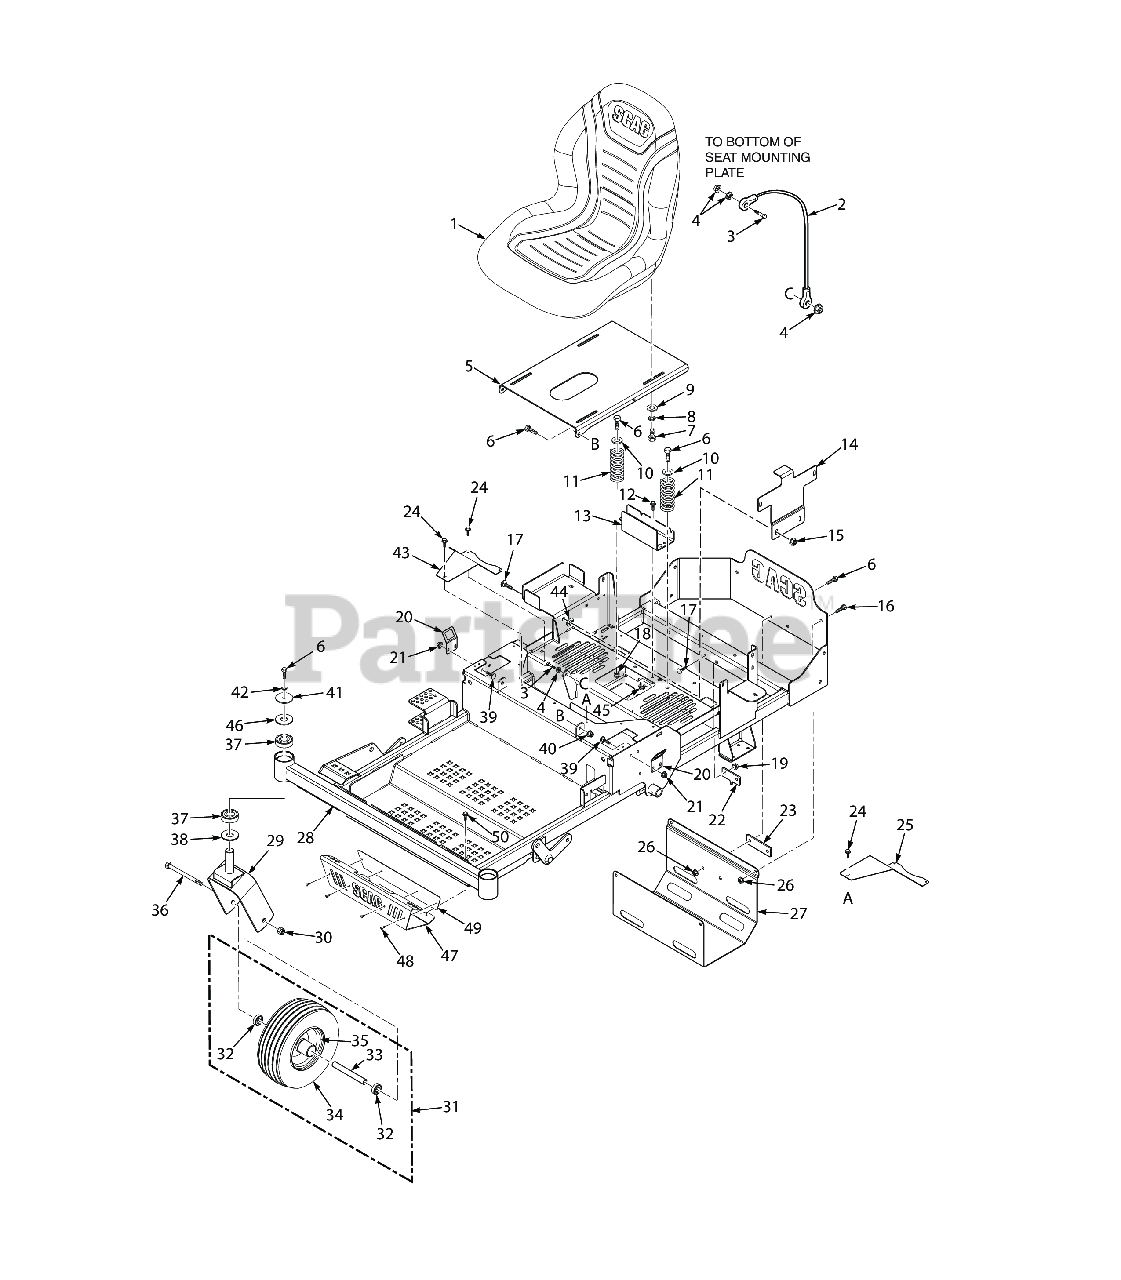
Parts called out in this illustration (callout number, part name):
1	Seat, SZL
2	Cable, Seat Stop
3	SERR. FLG. HEX HEAD CAPSCREW, 5/16-18 X 3/4
4	NUT, 1/4-20 SERRATED FLANGE HEX HEAD
5	Seat-Plate W/Decal
6	Bolt, Hex Head, 3/8-16 x 1 Gr. 5
7	BOLT, SERRATED FLANGE HEX HEAD 5/16-18 X 3/4"
8	Lockwasher, 5/16 (.317 x .586 x .078) Helical Spring
9	Flatwasher, 5/16-.375 x .875 x .083 (35BV & 37BV-EFI)
10	Flatwasher, 3/8" Special (.391 x .938 x .105)
11	Spring, Seat
12	Capscrew, 5/16-18 x .75 Serrated Flange Hex Head
13	Channel, Hose
14	Battery Hold Down
15	Nut, Flange Head Elastic Stop 5/16-18
16	Bolt, Hex Head, 3/8-16 x 3/4"
17	Bolt, 5/16-18 x .75 RHSN Carriage
18	HEX NUT, ELASTIC STOP LOCK, 3/8-16
19	Nut, Flange Head Elastic Stop 5/16-18
20	Bracket, Switch
21	Nut, Flanged Elastic Stop 1/4-20
22	PLATE, ANTI-ROTATION
23	Plate, Spacer
24	Screw, #10-32 x .563 Shakeproof
25	Guard, Belt - LH
26	NUT, 3/8-16 SERRATED FLANGE HEX HEAD
27	Skid Plate, SZL
28	Mainframe w/Decals - SZL
28	Mainframe w/Decals - SZL-61
29	Yoke Weldment, Caster
30	HEX LOCKNUT, ELASTIC STOP, 1/2-13
31	CASTER WHEEL ASSY, 11.00 X 6.00-5
32	Bearing
33	SPACER, WHEEL BEARING
34	TIRE, 11 X 6.00-5
35	RIM ASSY, 5 X 3 W/5.625 LG HUB
36	Bolt, Hex Head 1/2-13 x 7-1/2" (48"/52")
37	Bearing
38	Spacer, Yoke
39	Serr. Fl. Hex Head CPSCR, 1/4-20 x 3/4"
40	Nut, Flange Elastic Stop Nut, 3/8-16
41	Flatwasher, 3/8-.406 x 2.25" x .1875
42	Lockwasher, 3/8" Spring, Kawasaki FX / FS
43	Guard, Belt - RH
44	Nut, Push-On 5/16-18
45	Nut, Serrated Flange 5/16-18 (Right Front Engine Mounting, Briggs and Kohler Only)
46	Flatwasher, 7/16" (.500 x 1.25 x .083")
47	Front Bumper Assy.
48	Rivot, 3/16 x .402 POP
49	Background Plate
50	Screw, 1/4-20 x .375"
